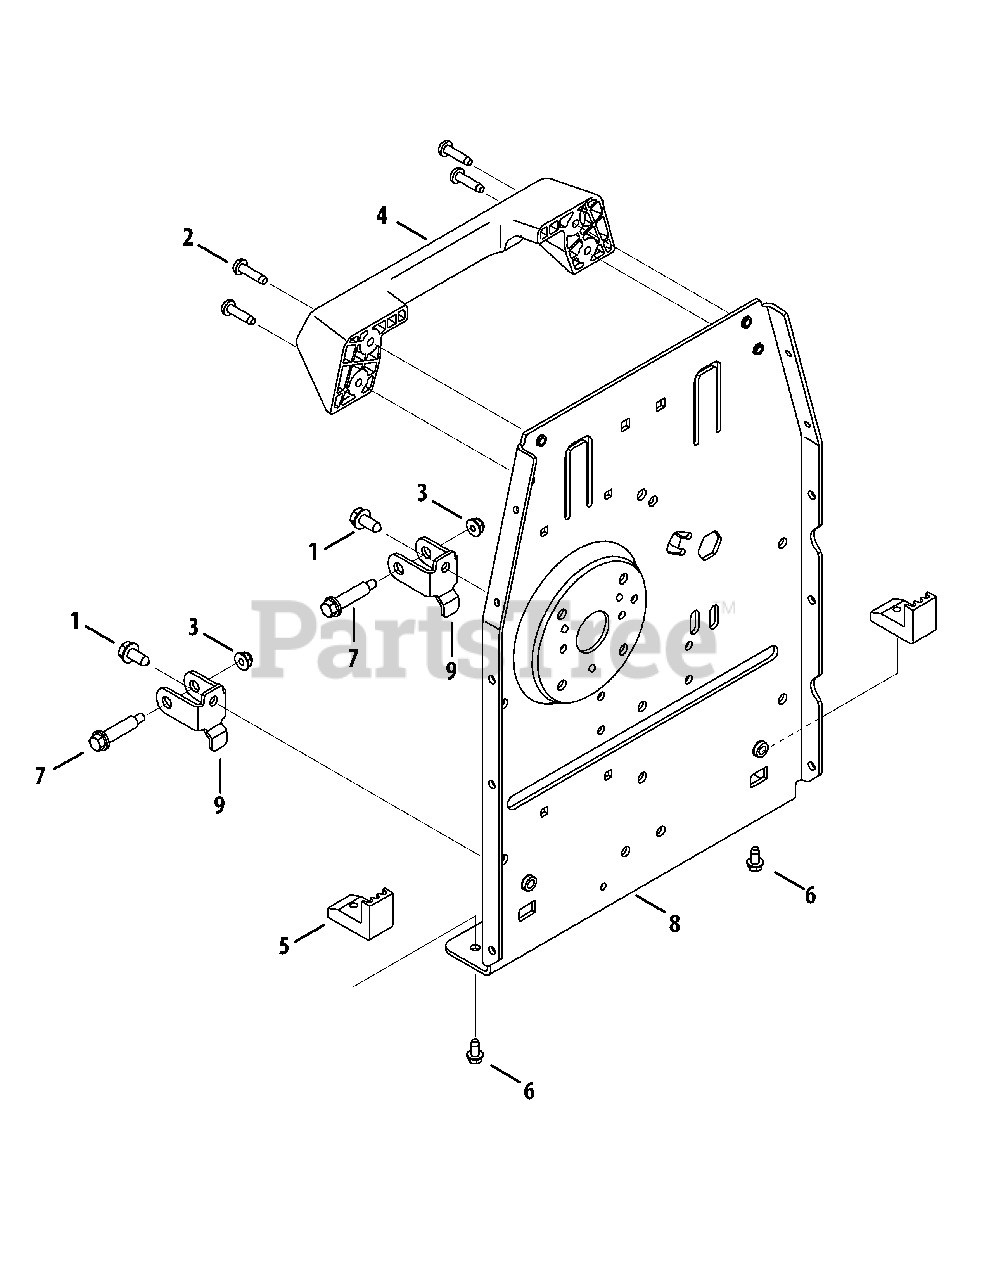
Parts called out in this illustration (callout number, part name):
1	Hex Washer Screw, 5/16-18 x .750
2	Self-tapping Screw, 1/4-20 x 1.00
3	Flange Lock Nut, 1/4-20
4	Rear Handle
5	Bumper Pad
6	Shoulder Screw, 1/4-20 x 0.50
7	Shoulder Screw,, 1/4-20 x .375 x 1.355
8	Frame Mounting Bracket
9	Support Bracket
